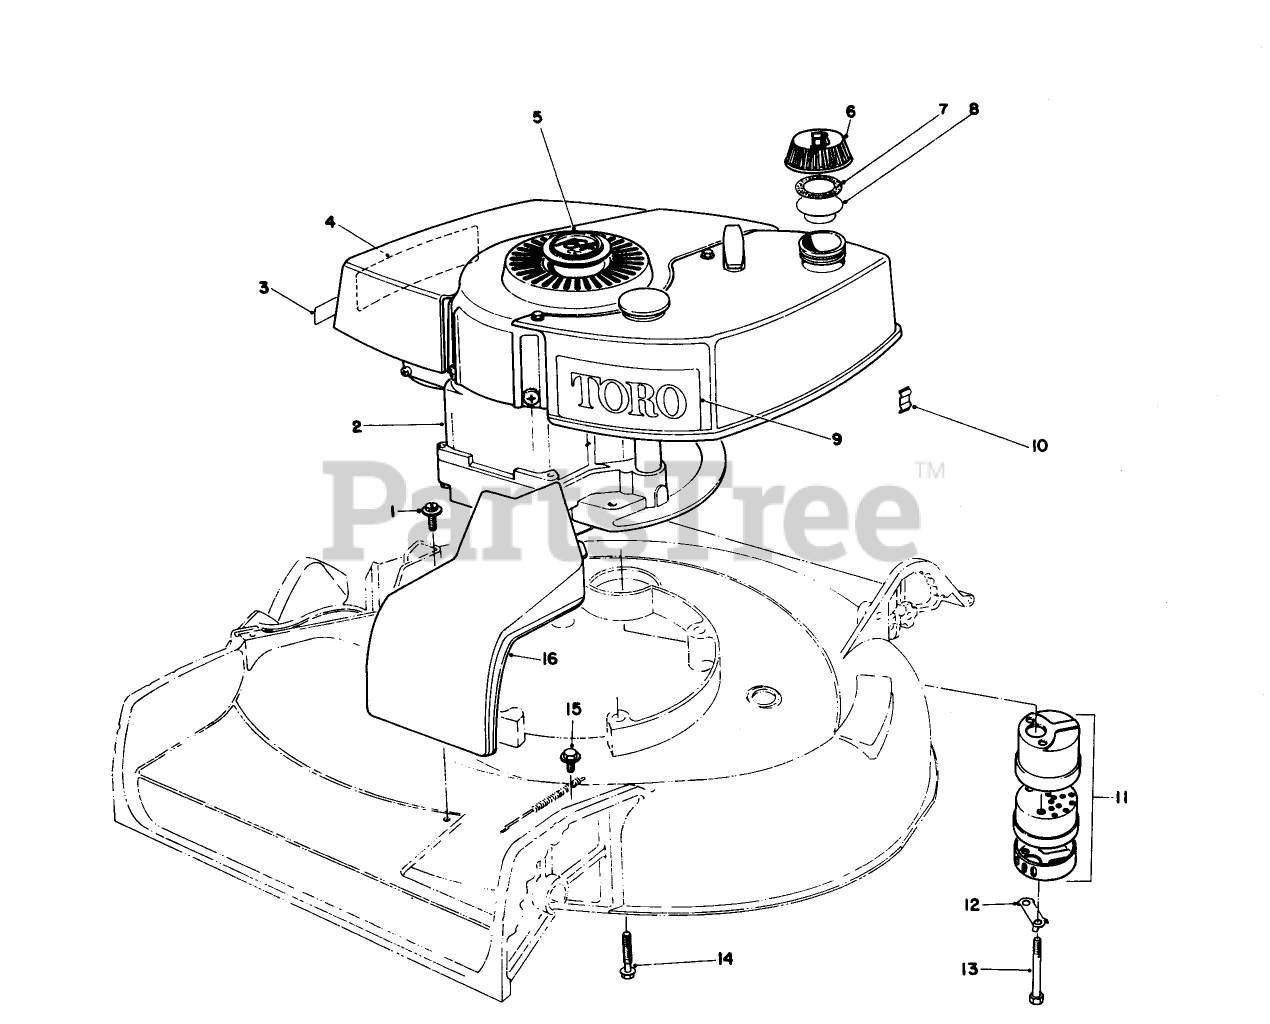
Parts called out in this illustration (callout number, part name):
1	SCREW
2	Engine
3	Decal-Primer Bulb
4	Decal Maintenance
5	Plug Button
6	Gas Cap Assembly (Incl.Ref. #7 & 8)
7	GASKET
8	GAS CAP BAFFLE
9	Decal Toro
10	Clip Conduit
11	Muffler (Incl. Ref. #12 & 13)
12	CLIP - LOCKING
13	SCREW-HH
14	3/8-16 X 2-3/4 CAPSCR
15	SCREW-HWHTF
16	Cover-Belt Drive
